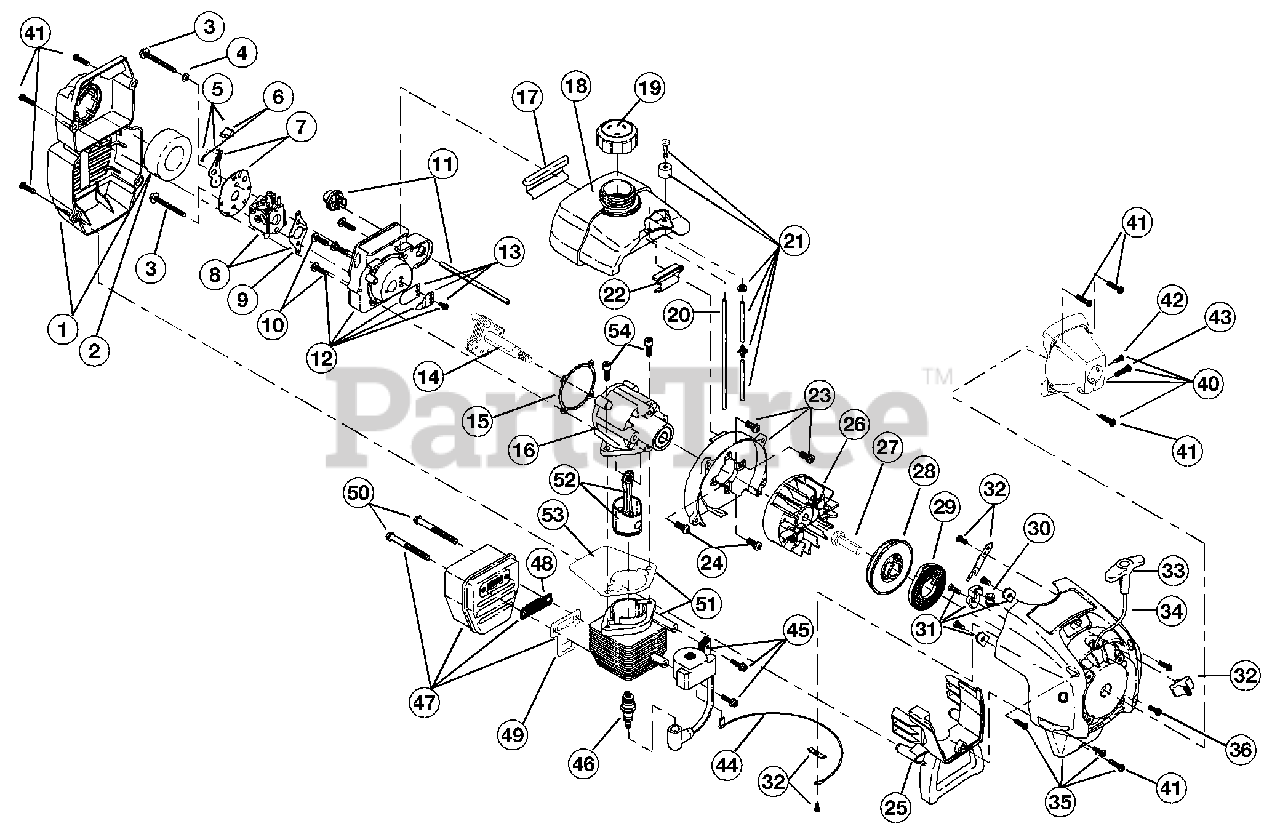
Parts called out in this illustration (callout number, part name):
1	Air Cleaner/Muffler Cover Assembly
2	Air Cleaner Filter
3	Carburetor Mounting Screw Assembly
4	Wavey Washer
5	Choke Lever Assembly
6	Choke Knob and Screw
7	Choke Lever and Plate
8	Carburetor Assembly W/Limiter Caps
9	Carburetor Gasket
10	Carb Mount Screw
11	Primer and Hose Assembly
12	Carb Mount Assembly
13	Reed Assembly
14	Power Shaft Assembly
15	Carburetor Mount Gasket
16	Crank Case Service Assembly
17	Rear Mounting Pad
18	Fuel Tank Assembly
19	Fuel Cap Assembly
20	Fuel Return Line
21	Fuel Line Assembly
22	Front Mounting Pad
23	Shroud Assembly
24	Shroud Screw
25	Shroud Extension and Stand
26	Flywheel Assembly
28	Recoil Pulley Assembly
29	Recoil Spring
30	Rope Guide
31	Pulley Retainer Assembly
32	Switch Assembly
33	Pull Handle
35	Starter Housing Assembly
36	Housing Screw
37	Clutch Washer
38	Clutch Rotor Assembly
39	Clutch Drum Assembly
40	Clutch Cover Assembly
41	Cover Screw
42	Anti-Rotation Screw
43	Clamping Screw
44	Wire Lead
45	Module Assembly
46	Spark Plug
47	Muffler Assembly
48	Spark Arrestor Screen
49	Exhaust Gasket
50	Muffler Mounting Bolt Assembly
51	Cylinder Assembly
52	Piston and Rod Assembly
53	Cylinder Gasket
54	Cylinder Bolt
